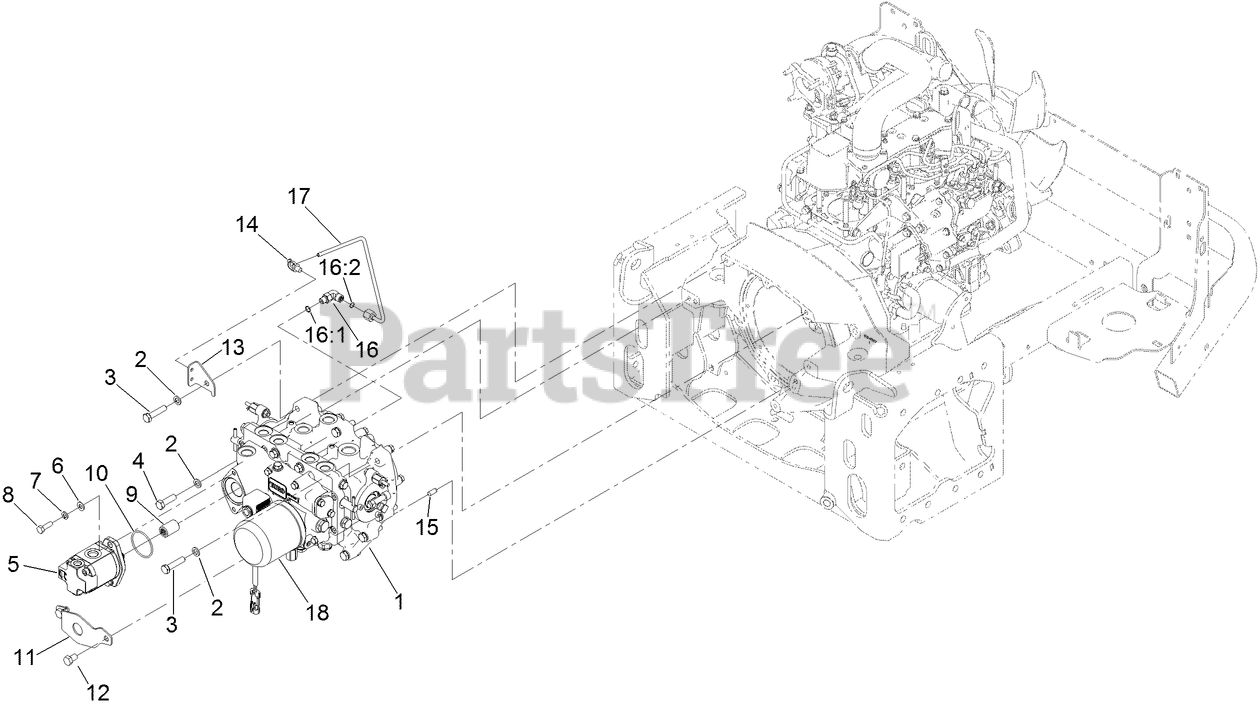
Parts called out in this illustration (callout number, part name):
1	TRANSMISSON ASM
2	WASHER-LOCK
3	SCREW-HH
4	SCREW-HH
5	HYD GEAR PUMP ASM
6	WASHER-PLAIN
7	WASHER-LOCK
8	SCREW-HH
9	COUPLER-SPLINE
10	O-RING
11	SHIELD-SEAL
12	SCREW-HH
13	SUPPORT-TUBE
14	CLIP-TIE
15	PIN-DOWEL
16	FITTING-ELBOW, 90 DEG
16:1	O-RING
16:2	O-RING
17	TUBE ASM
18	FILTER-OIL, HYD
